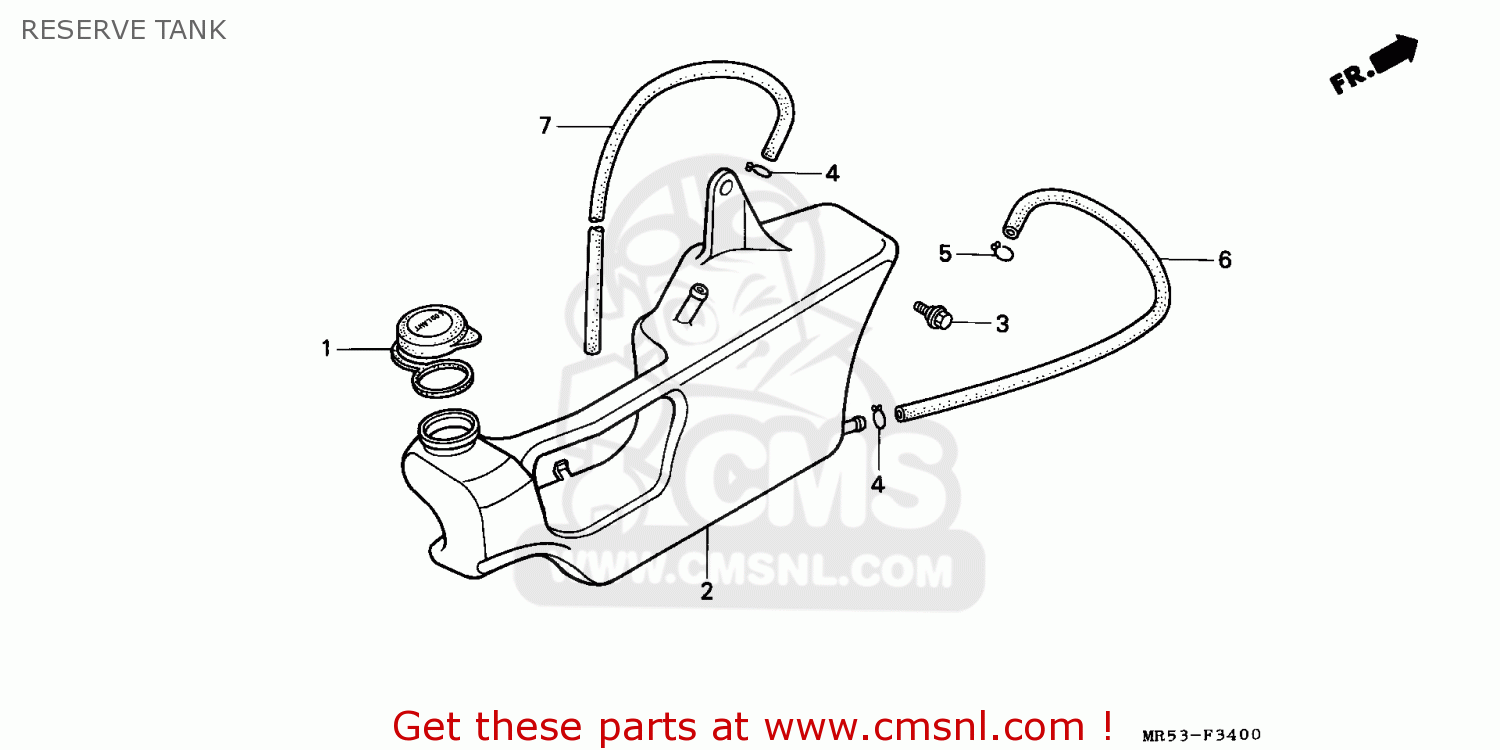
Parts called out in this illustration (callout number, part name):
1	CAP,RESERVE TANK
2	TANK RAD RESERVE
3	BOLT,FLANGE 6MM
4	CLIP B12,TUBE
5	CLIP C11,TUBE
6	TUBE 7.3X400
7	TUBE 7.5X700
